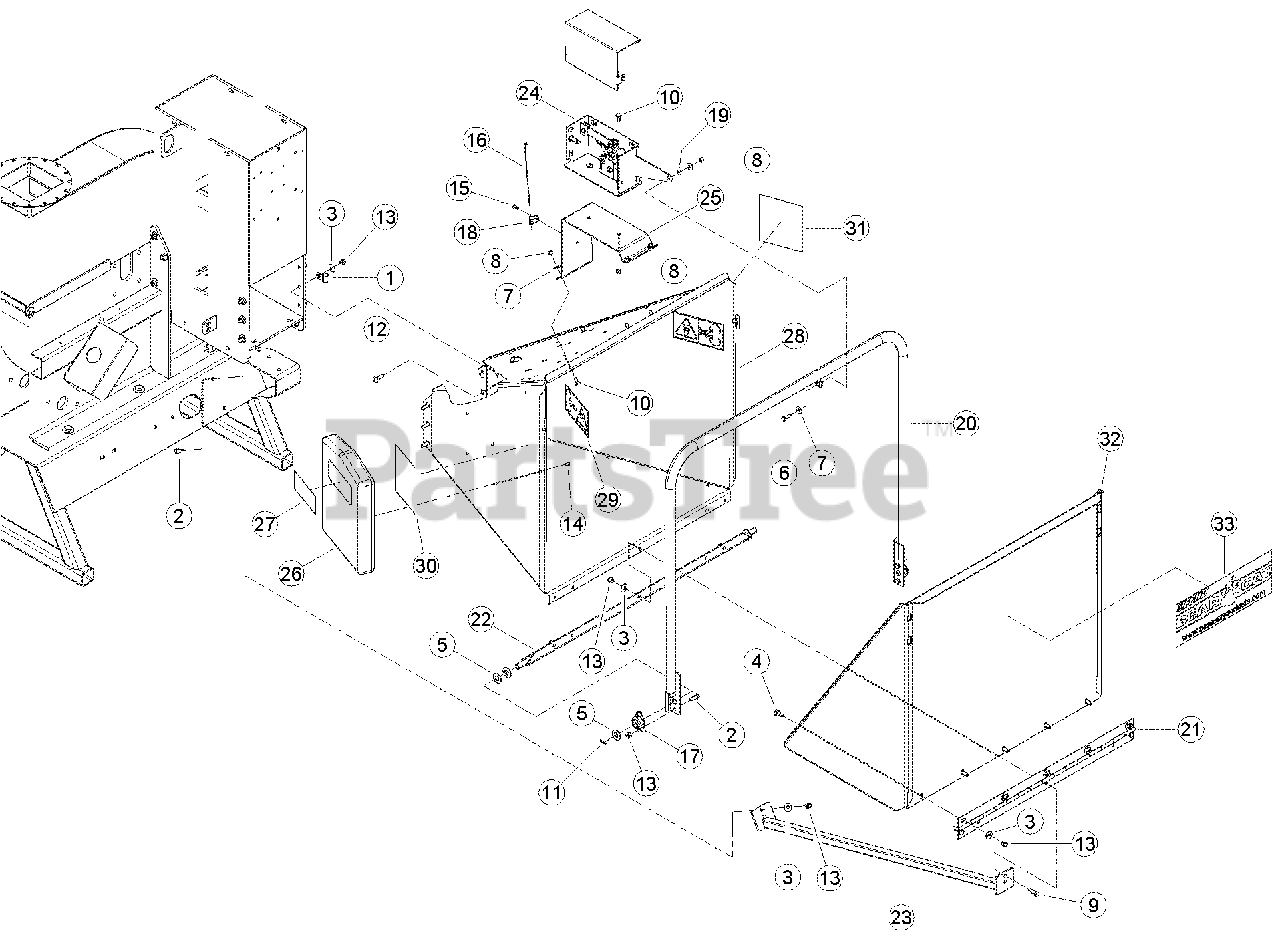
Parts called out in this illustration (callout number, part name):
1	CLAMP, 9/16" COATED
2	BOLT, 3/8 X 1 HEX HD GR5 ZP
3	WASHER, 3/8 FLAT ZP
4	BOLT, 3/8 X 1 CRG GR5 NC ZP
5	WASHER, 5/8 SAE FLAT ZP
6	BOLT, 5/16 X 1 HEX HD GR5 NC ZP
7	WASHER, 5/16 FLAT ZP
8	NUT, 5/16 NE NYLOCK ZP
9	BOLT, 3/8 X 1-1/4 HEX HD GR5 ZP
10	BOLT, 5/16 X 3/4 CRG GR5 NC ZP
11	PIN, 1/8 X 1.00 ZP COTTER
12	BOLT, 3/8 X 1-1/4 CRG GR5 NC ZP
13	NUT, 3/8 NE NYLOCK ZP
14	RIVET, AL BLIND 1/4 X 1/2 DOME HEAD
15	RIVET, AL BLIND 1/4 X 3/4 DOME HEAD
16	STRAP, 11 IN. BLACK TIE
17	BEARING, SIDE FLNG MOUNT,5/8"
18	CLAMP, CABLE MOUNT
19	SPACER, IDLER PIVOT
20	WELDMENT, CONTROL ARM
21	HINGE, EXTENSION TRAY
22	WELDMENT, CONTROL PIVOT
23	WELDMENT, CHUTE SUPPORT
24	ASSEMBLY, SWITCH BOX
25	MOUNT, SWITCH BOX
26	ASSEMBLY, MANUAL CONTAINER SERVICE PART
27	DECAL, MUTILINGUAL MANUAL
28	ASSEMBLY, BIG CHIPPER CHUTE SERVICE PART
29	DECAL, BLADE DANGER ISO
30	DECAL, FEED POSITION
31	DECAL, FEED POSITION
32	ASSEMBLY, CHUTE EXTENSION TRAY SERVICE PART
33	DECAL, BEARCAT WEB
